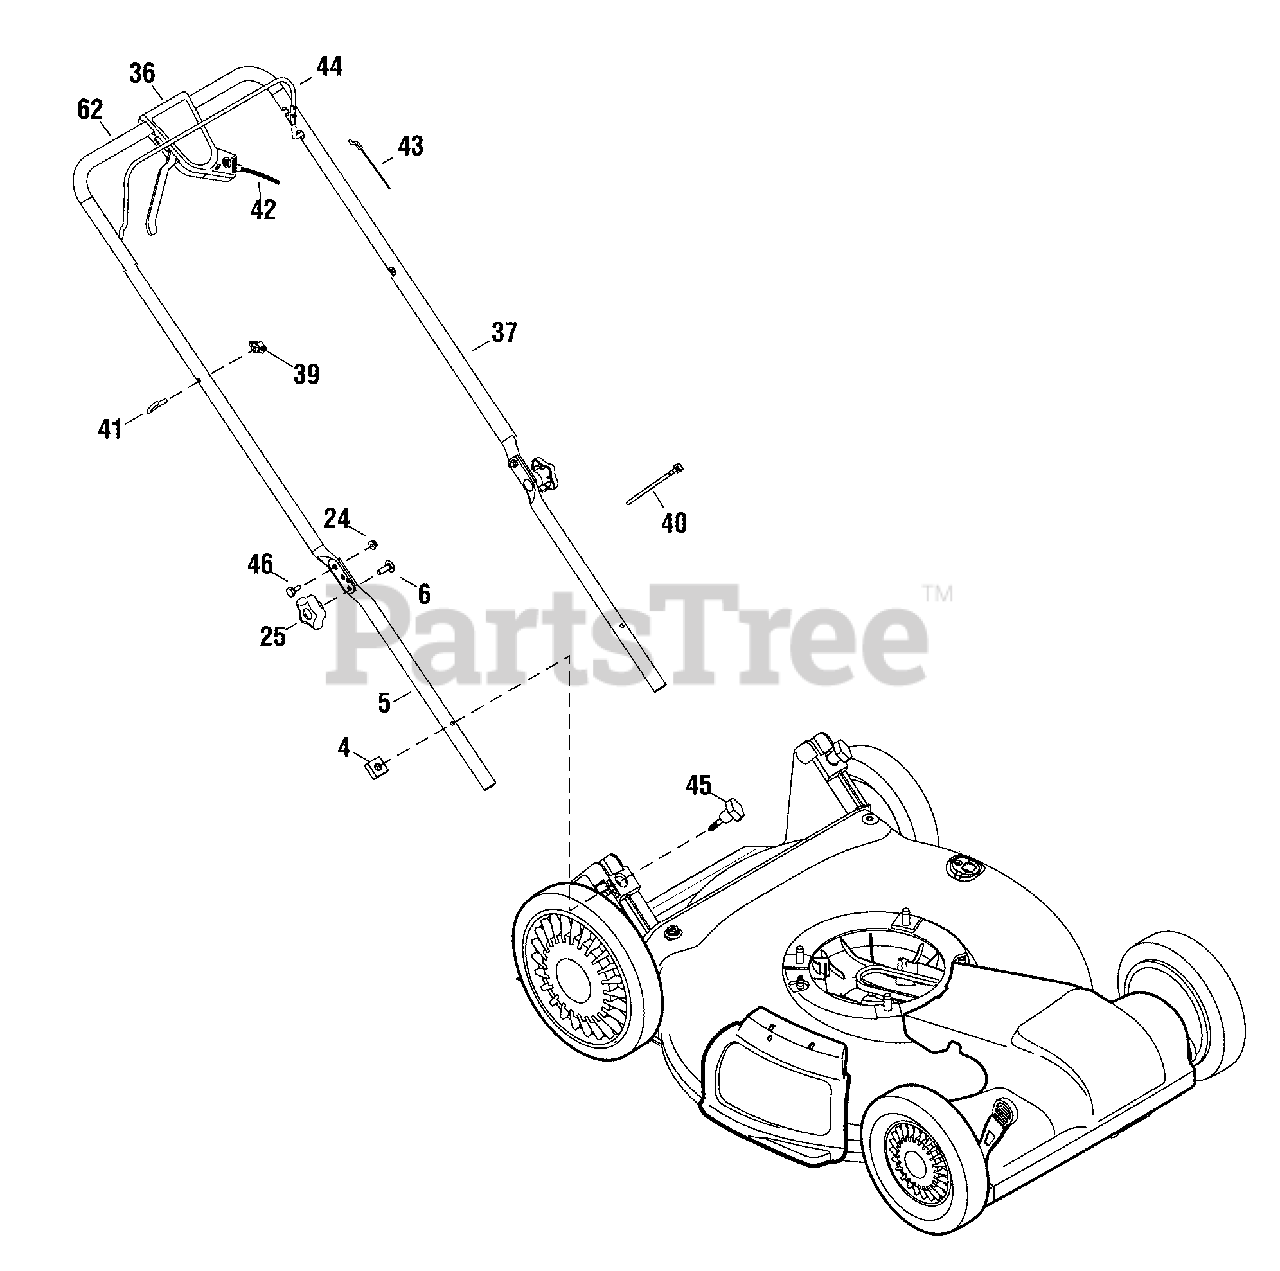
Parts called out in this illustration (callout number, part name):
4	NUT, Square, 1/4-20
5	HANDLE, Lower
6	BOLT, Carriage, 5/16-18 x 1, GR5
24	NUT, Nylock Flanged, 1/4-20
25	KNOB, Wing, 5/16-18
36	ASSEMBLY, Control Lever
37	HANDLE, Upper
39	KNOB, 1/4-20
40	TIE, Self Lock
41	GUIDE, Rope
42	CABLE, Control
43	CABLE, OPC Engine Brake
44	BAIL, Blade Control
45	NUT, Wing
46	BOLT, Shoulder, 1/4-20
62	GRIP, Foam
